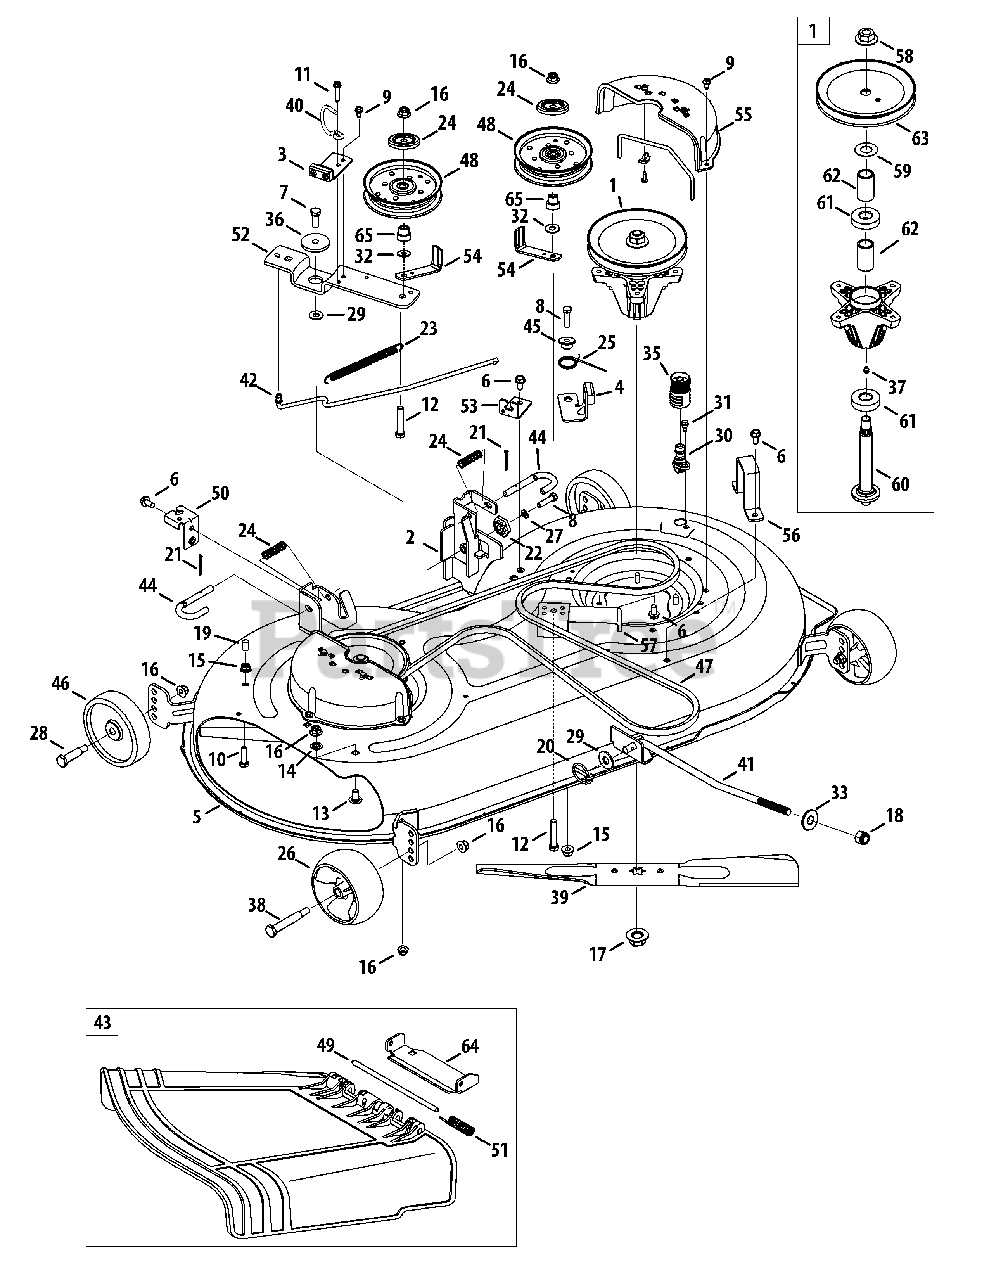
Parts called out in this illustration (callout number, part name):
1	Pulley Spindle Ass’y 6.3 dia.
2	Deck Hanger Bracket Ass’y LH
3	Deck Brake Assembly
4	Deck Brake Assembly
5	Deck, 42"
6	S-Tapp Scr 5/16-18 x .75
7	Hex Screw, 3/8-16, 1.25, Gr5, Std
8	Hex Wash Tap Scr 5/16-18 x 1.25
9	Hex Wash S-Tapp Scr 1/4-20 x .50
10	Hex Cap Screw, 5/16-18 x 1.00
11	Hex Bolt 1/4-20 x .75
12	Hex. Hd. Cap Scr. 3/8-16 x 2.0 Gr. 5
13	Carriage Bolt 3/8-16 x .75 Gr. 1
14	Push Nut, 3/8
15	Hex Flange Locknut 5/16-18 Gr. F, Nylon
16	Hex Flange Locknut 3/8-16 Gr. F, Nylon
17	Hex Flange Locknut 5/8-18
18	Hex Locknut 1/2-13
19	Cap, .290 x .500
20	Lynch Pin
21	Cotter Pin 1/8 x 1.75
22	Deck Gear Adjuster
23	Extension Spring .62 dia. x 6.12 Lg.
24	Compression Spring .535 x 1.751
25	Torsion Spring .992 ID x 1.17 OD
26	Deck Wheel 5.0 Dia.
27	L-Wash 5/16 ID
28	Shoulder Bolt .496 x 1.525, 3/8-16
29	Flat Washer .531 ID x 1.25 OD x .100
30	Deck Water Nozzle
31	Shoulder Screw 1/4-20 x 0.50
32	Flat Washer .385 ID x .870 OD x .092
33	Cupped Washer .63 x 1.25 x .18
34	Pulley Cap
35	Water Nozzle Adapter
36	Shoulder Spacer .8540 x .200
37	Grease Fitting
38	Shoul der Bolt .496 x 2.5, 3/8-16
39	Blade, 21.23", 2-in-1
40	Belt Keeper Rod
41	Front Lift Deck Rod
42	Brake Control Rod
43	Side Discharge Chute Assembly
44	Deck Release Pin
45	Shoulder Spacer .50 x .145
46	Deck Wheel
47	V-Belt
48	Idler Pulley w/Flange 4.25 Dia.
49	Hinge Pin .3125 diam. x 7.96" Lg.
50	Cable Bracket Deck Engage
51	Torsion Spring .44 ID x 2.0
52	Idler Pivot Bracket
53	Deck Cable Engagement Bracket
54	Belt Guard Pulley Bracket
55	Belt Cover
56	Deck Lift Pivot Cup
57	Deck Support Stationary Idler Brkt.
58	Hex Flange Locknut 5/8-18
59	Flat Washer .760 ID x 1.5 OD
60	Spindle Shaft 6.11" Lg.
61	Ball Bearing .787 ID x 1.85 OD x .551
62	Spacer .792 x 1.060 x 1.860
63	Deck Pulley 6.3 dia.
64	Chute Bracket
65	Idler Shoulder Spacer
